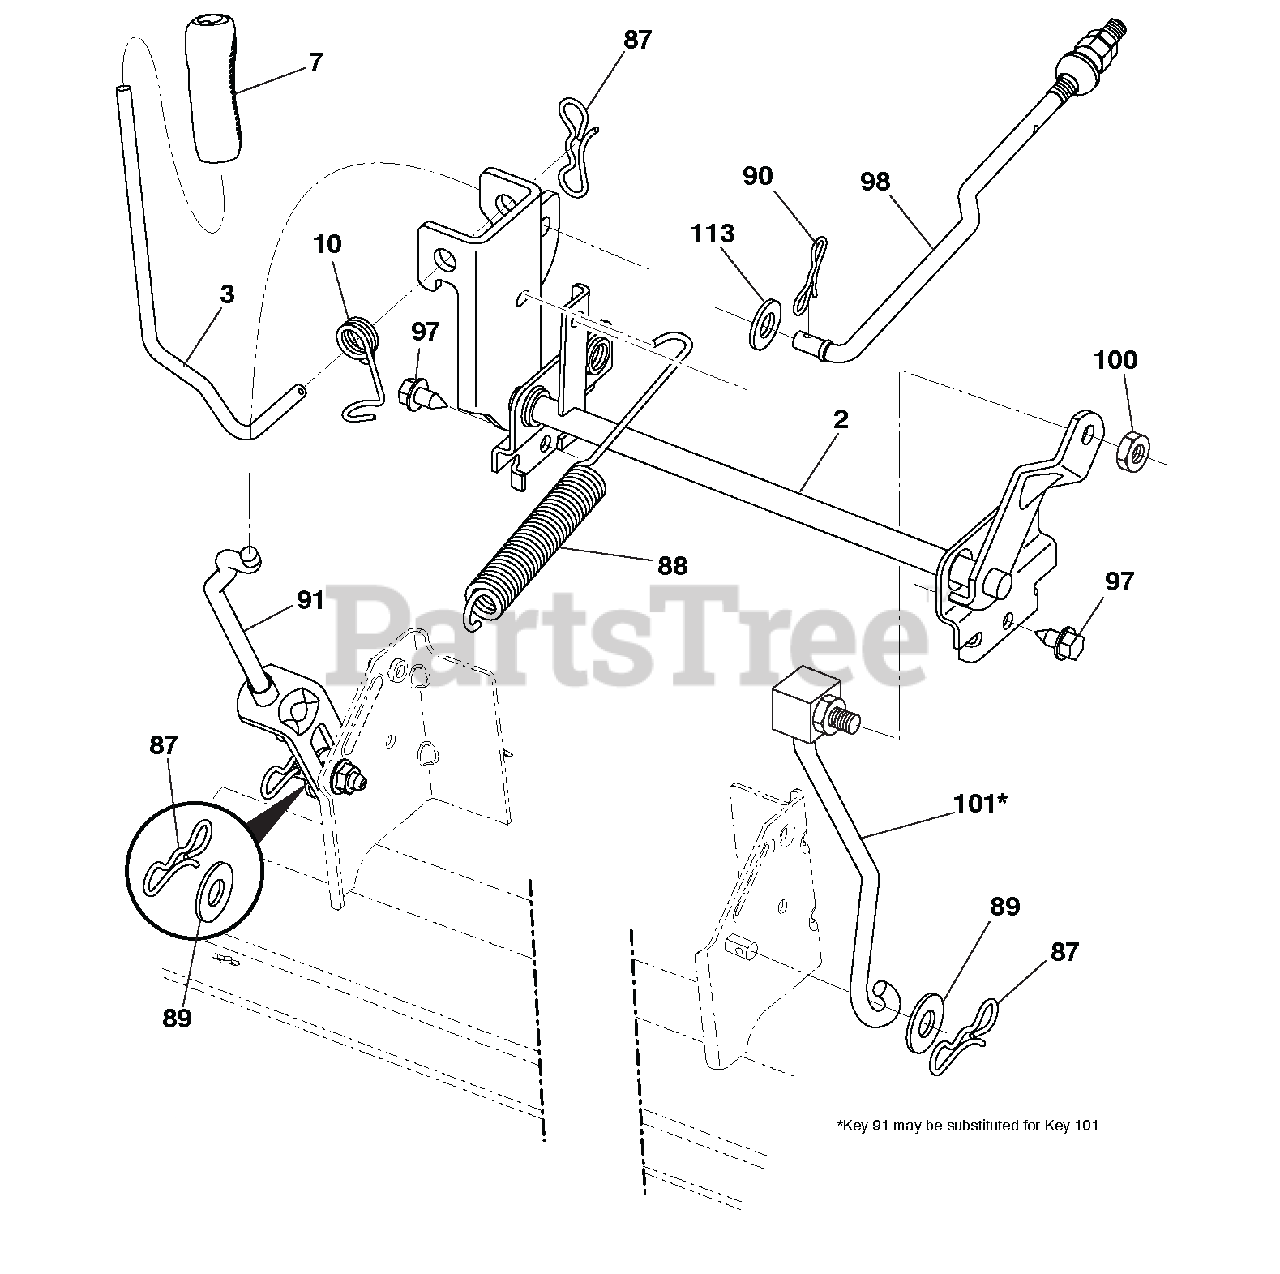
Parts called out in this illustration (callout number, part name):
2	SHAFT ASM.LIFT.CROSS.HD.
3	LEVER.LIFT.HANDLE.LT
7	GRIP LEVER 5625 LD BLACK 428
10	SPRING.TORSION.HANDLE.LIFT
87	PIN.COTTER.7/16.BOW TIE LOCK
88	SPRING.LIFT ASSIST
89	WASHER.CLEAR ZINC
90	PIN.COTTER.5/16.BOW TIE LOCK
91	LINK ASM.LIFT.LH.REAR
97	SCREW.HEXWSH THDR3/8-16X3/4.BL
98	LINK ASM.SUSP.FRONT.MWR.10.5
100	NUT.CENTERLOCK.3/8-16 UNC.
101	LINK ASM.LIFT.FIXED.38/42/46"
113	WASHER.17/32 X 1-3/16 X 12 GA.
